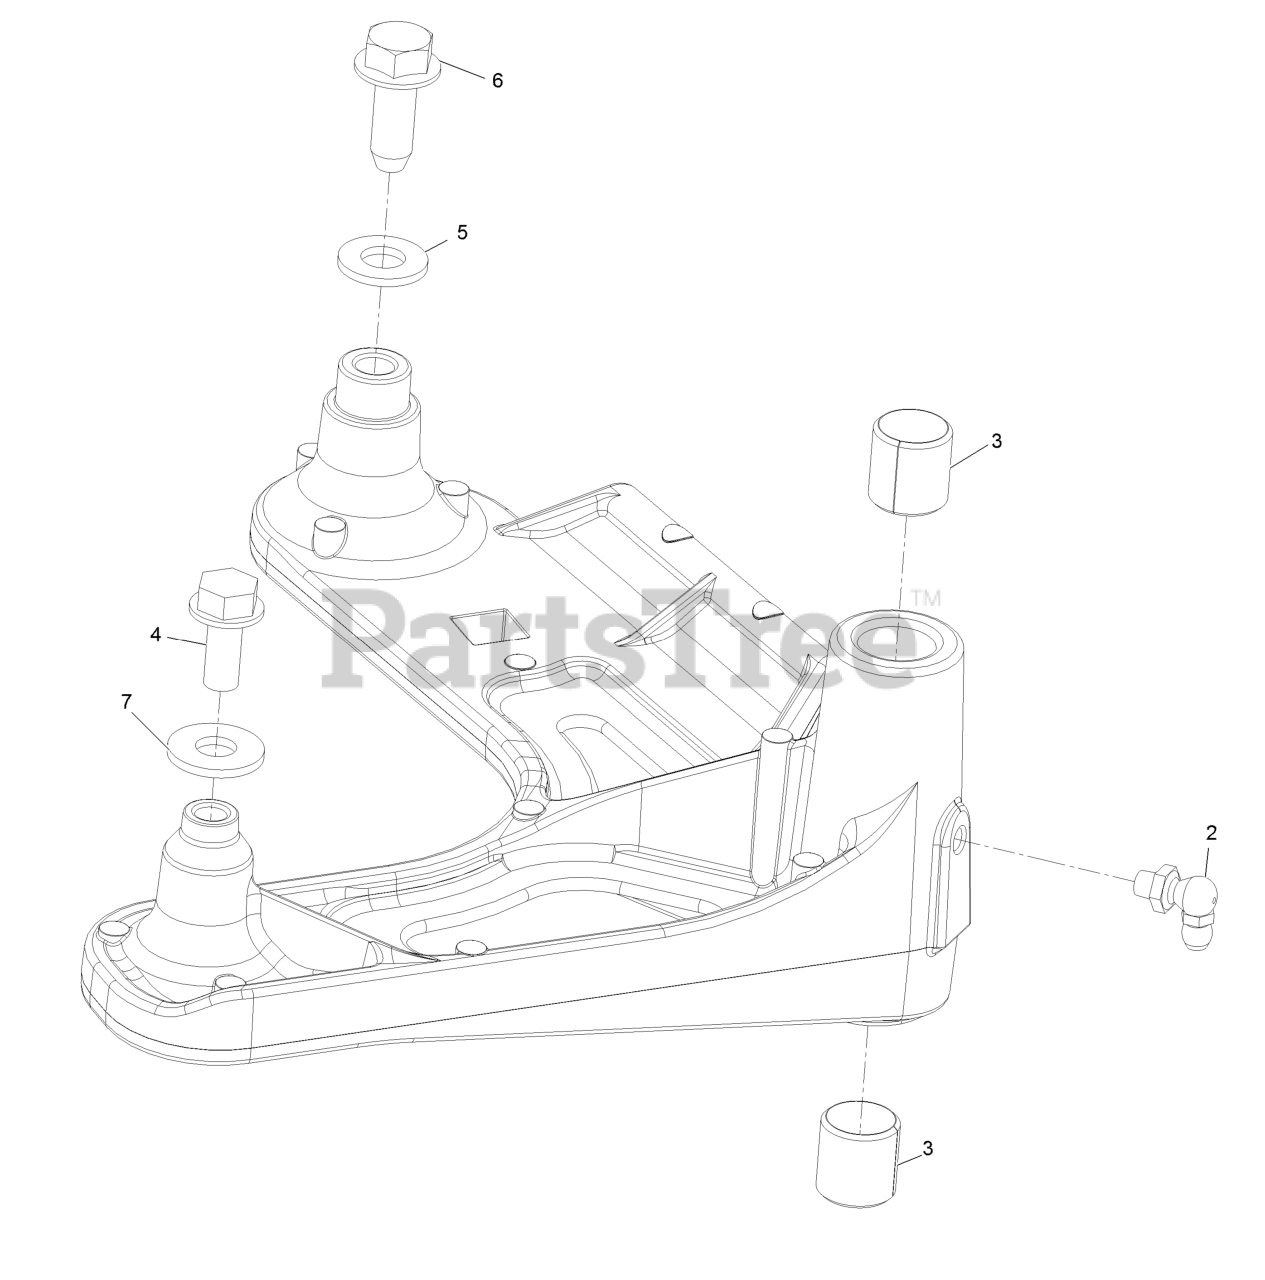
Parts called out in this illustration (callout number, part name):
2	Zerk-90deg 1/4-28
3	Sleeve-Bearing
4	Screw-HWH 5/16-18 X 3/4 Tf
5	Washer-3/8 SAE
6	Screw-Forming, Thread
7	Washer-5/16 Std
